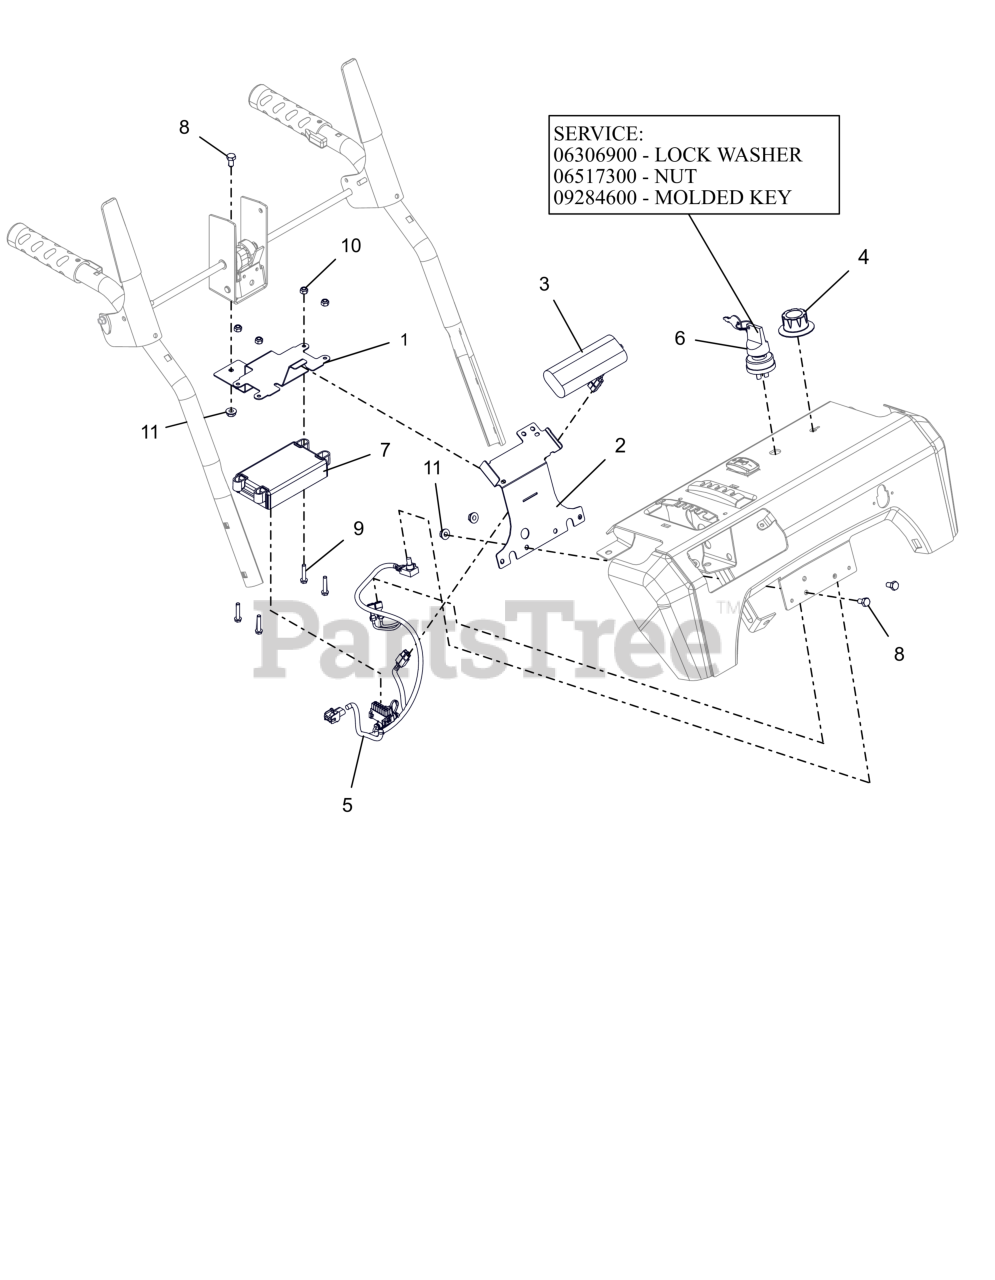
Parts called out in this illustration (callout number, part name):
1	BRACKET, ENGINE EFI-LCT LOWER
2	BRACKET, ENGINE EFI-LCT UPPER
3	BATTERY, SNOW EFI - 7.2V
4	KNOB, CONTROL - 2.063 ID
5	HARNESS,WIRE - EFI ECU
6	IGNITION SWITCH ASM - 2 POS
6	WSHR-LK-INT .625X.045 YWZC
6	NUT-PANEL .625-32 GRECO
6	KEY W/ SHIELD
7	ECU SERVICE LCT/CSI - 306CC
8	BLT,HEX .25-20X.50 G5 ZCC
9	BLT, HWH #10-24X1.00 ZCC
10	NUT-LK-NYL #10-24 G2 ZCC
11	NUT-LK-TOP-FLG .250-20 GF ZCC
